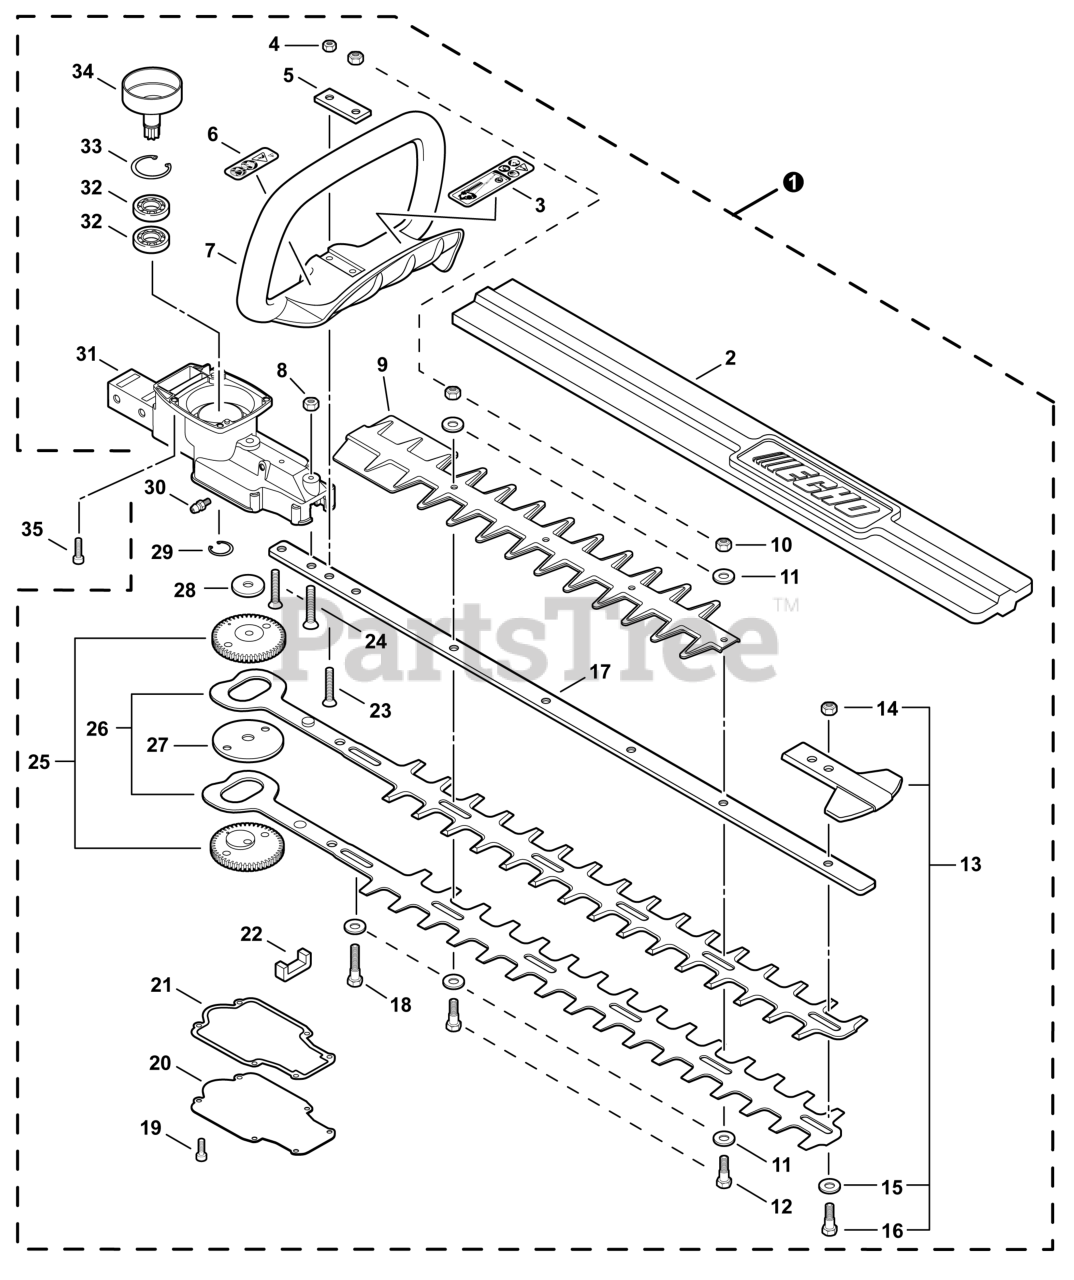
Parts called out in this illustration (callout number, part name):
1	CUTTING HEAD KIT
2	SCABBARD 24"
3	LABEL - CAUTION - ISO
4	NUT, FLANGE M5
5	PLATE, EYE
6	LABEL - CAUTION
7	HANDLE, FRONT
8	NUT, HEX M6
9	GUARD, CUTTER BLADE
11	WASHER 6.5×15.5×0.6
12	BOLT 6×18
13	TIP GUARD KIT
15	WASHER 6.5×15.5×0.6
16	BOLT 6×18
17	SUPPORT, BLADE
18	BOLT M6×35
19	BOLT, TORX 4×12
20	COVER, GEAR CASE
21	GASKET, GEAR CASE
23	SCREW 5×30
24	SCREW 6×30
25	GEAR, SPUR
27	WASHER 50
28	WASHER 30
29	RING, SNAP 14
30	FITTING, GREASE
31	CASE, GEAR
32	BEARING, BALL 6202
33	RING, SNAP 35
34	DRUM, CLUTCH
35	BOLT, TORX 4×16
